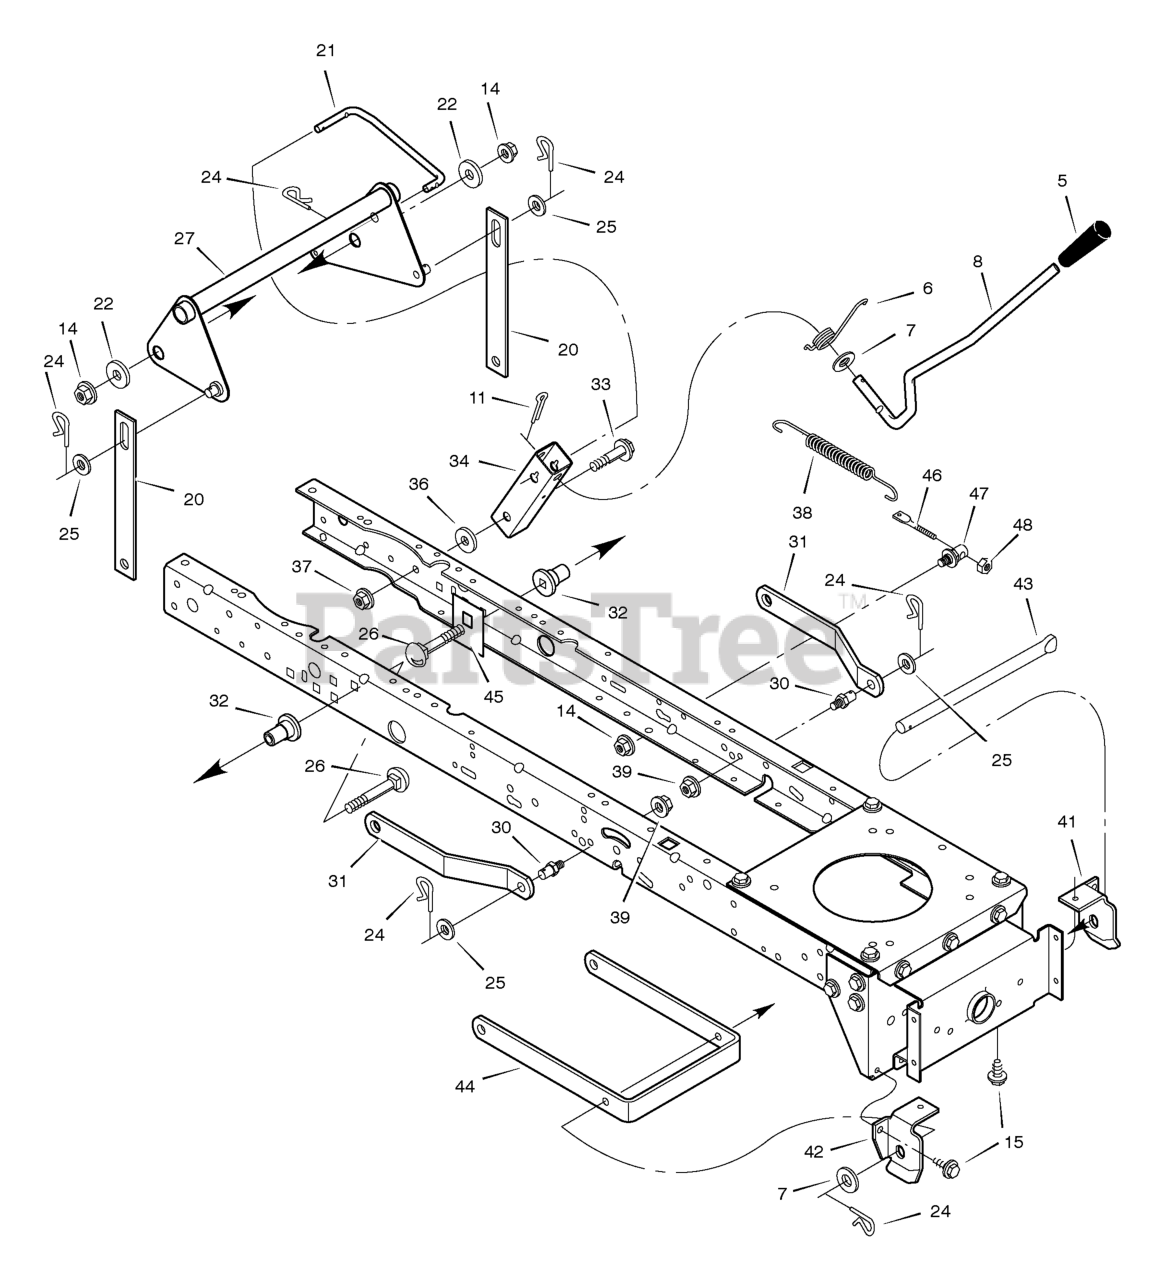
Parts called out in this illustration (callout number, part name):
5	Grip
8	Lever, Lift
11	Pin, Cotter
14	Nut, Flange
20	Link, Lift
21	Link, Lift Handle
24	Pin, Hair
26	Bolt, Carriage
27	Lever Assembly, Lift
30	Pin
31	Bracket, Rear Suspension
32	Spacer, Lifter
33	Bolt, Shoulder
34	Bracket, Pivot
37	Nut, Flange
39	Nut, Flange
41	Hanger, Left Deck
42	Hanger, Right Deck
43	Rod, Hanger
44	Bracket, Suspension
45	Plate, Stiffening
46	Stud, Spring Mount
47	Stud, Swivel
48	Nut
